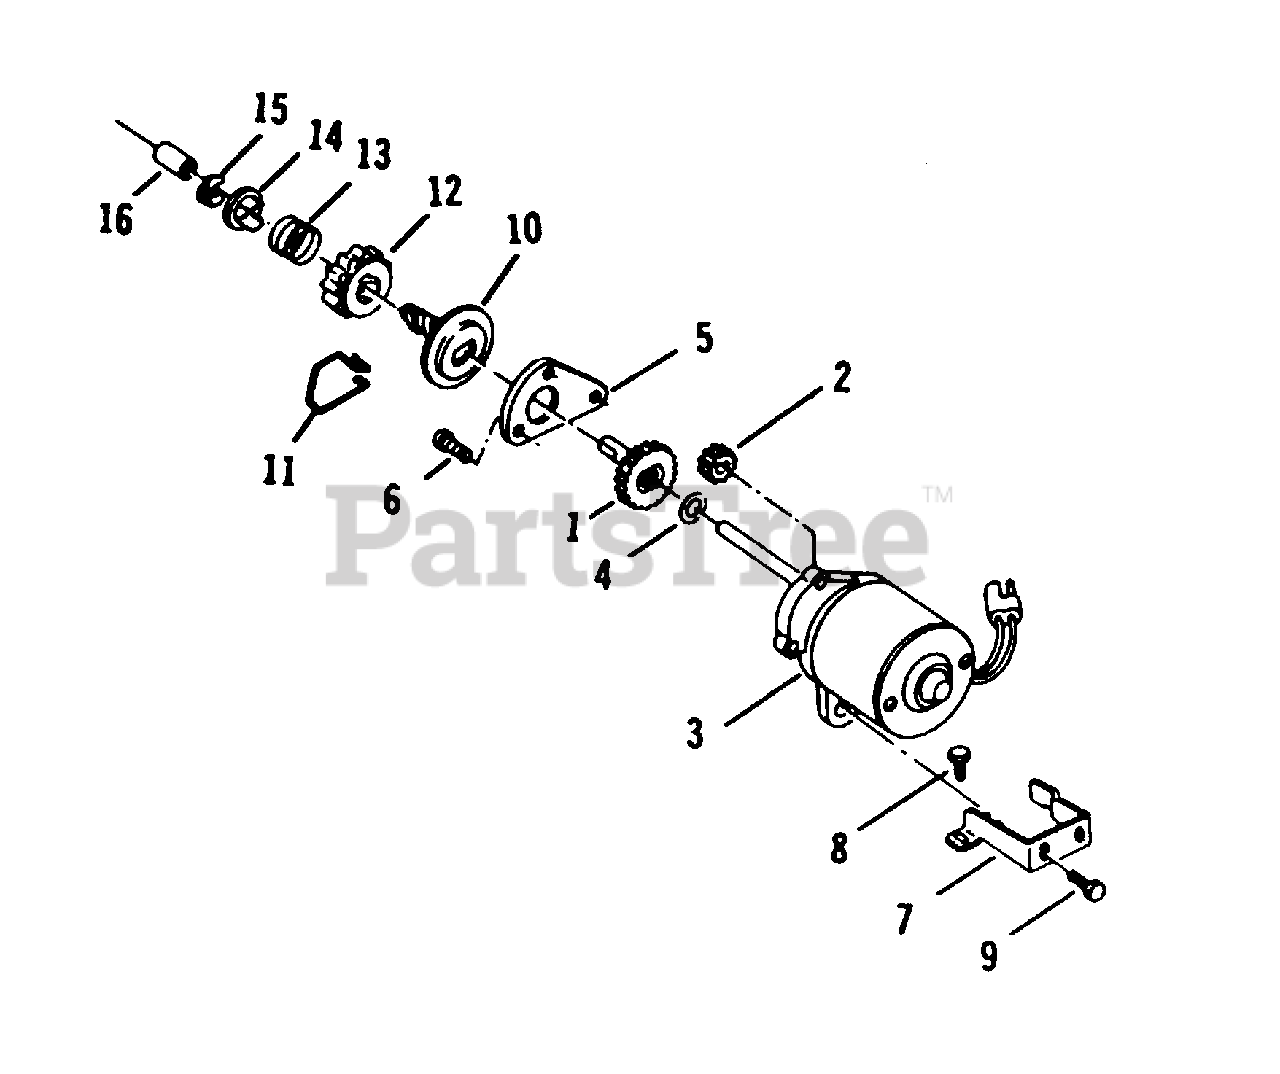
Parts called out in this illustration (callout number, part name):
1	Gear-Driven
2	Pinion-Motor Shaft
3	Motor Housing and Pin Assy.
4	Washer
5	Plate-Gear Cover
6	Screw
7	Bracket-Starter Mtg.
8	Screw
9	Screw
10	Pinion, Spring and Clutch Assy.
11	Spring-Drag
12	Pinion
13	Spring-Pinion Return
14	Washer-Pinion Stop
15	Retaining Ring
16	Sleeve
